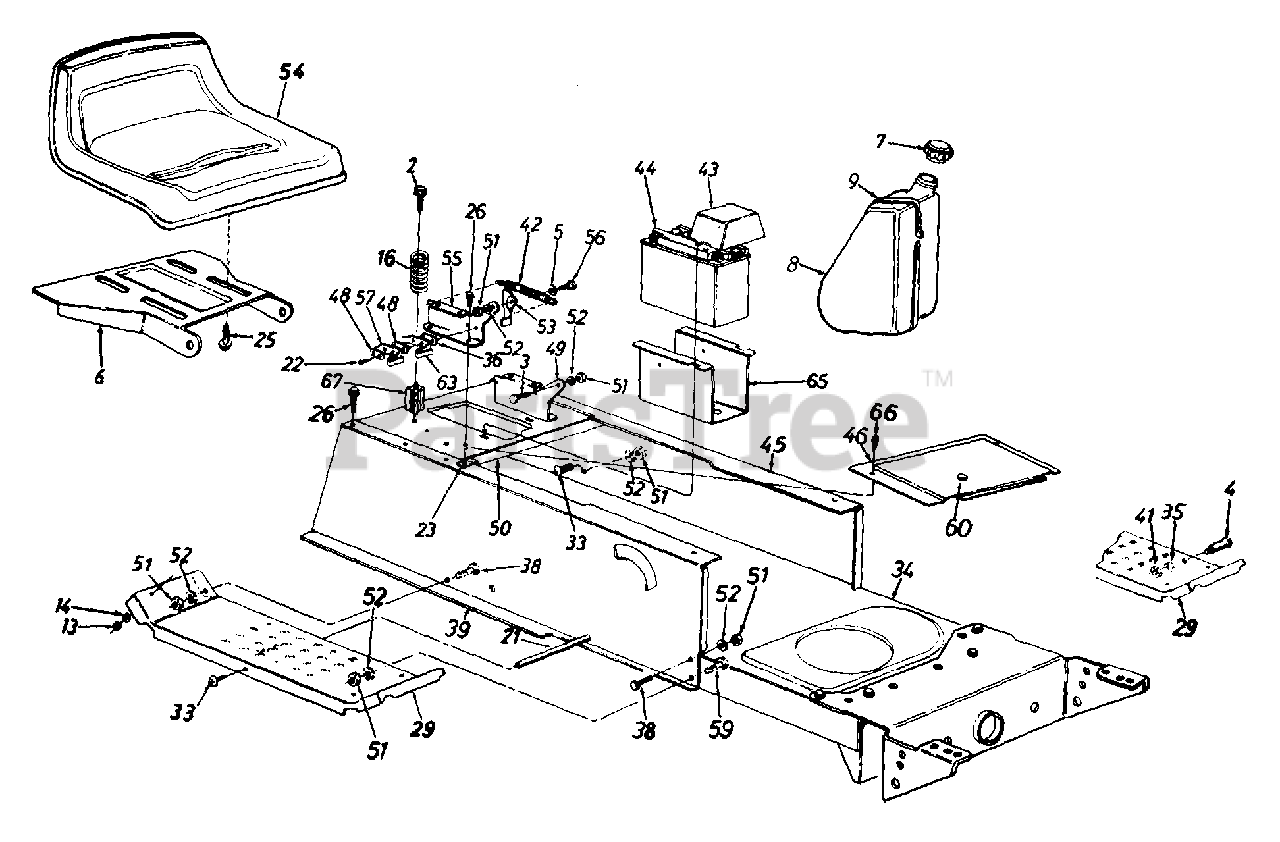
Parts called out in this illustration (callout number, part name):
2	Hex Wash. Hd. Tap Scr. 5/16-18 x 3.25" Lg.
3	Shld. Bolt .437" Dia. x .162"
4	Shld. Bolt .50" Dia. x .84"
5	Spr-Wash. .445" I.D. x .75
7	Fuel Cap
9	Tie Strap
13	Hex Nut 1/4-20 Thd.
14	L-Wash. 1/4" I.D.
16	Compression Spring
21	Running Board Rod
22	Hex Wash. Hd. AB-Tap Scr. #8 x .50" Lg.
23	Speed Nut #10Z
25	Hex Tap Scr. 3/8-16 x .75"
26	Hex Wash. Hd. AB-Tap Scr. 5/16 x .75" Lg.
36	Insulator Boss Plate
38	Hex Bolt 5/16-18 x .75" Lg.
39	Upper Frame - R.H.
41	Hex Nut 3/8-16 Thd.
42	Extension Spring 5.31" Lg.
43	Battery Cover
44	12-V Battery
45	Upper Frame - L.H.
52	L-Wash. 5/16" I.D.
53	Seat Lift Brkt.
54	Seat
56	Shld. Bolt .437" Dia. x .268"
57	Spring Switch
59	Hex Wash. TT-Tap Scr. 5/16-18 x 7/8" Lg.
60	Snap Bushing
63	Safety Switch (Seat)
65	Battery Tray
66	Truss Mach. B-Tap Scr. #10 x .5" Lg.
67	Spring Spacer
